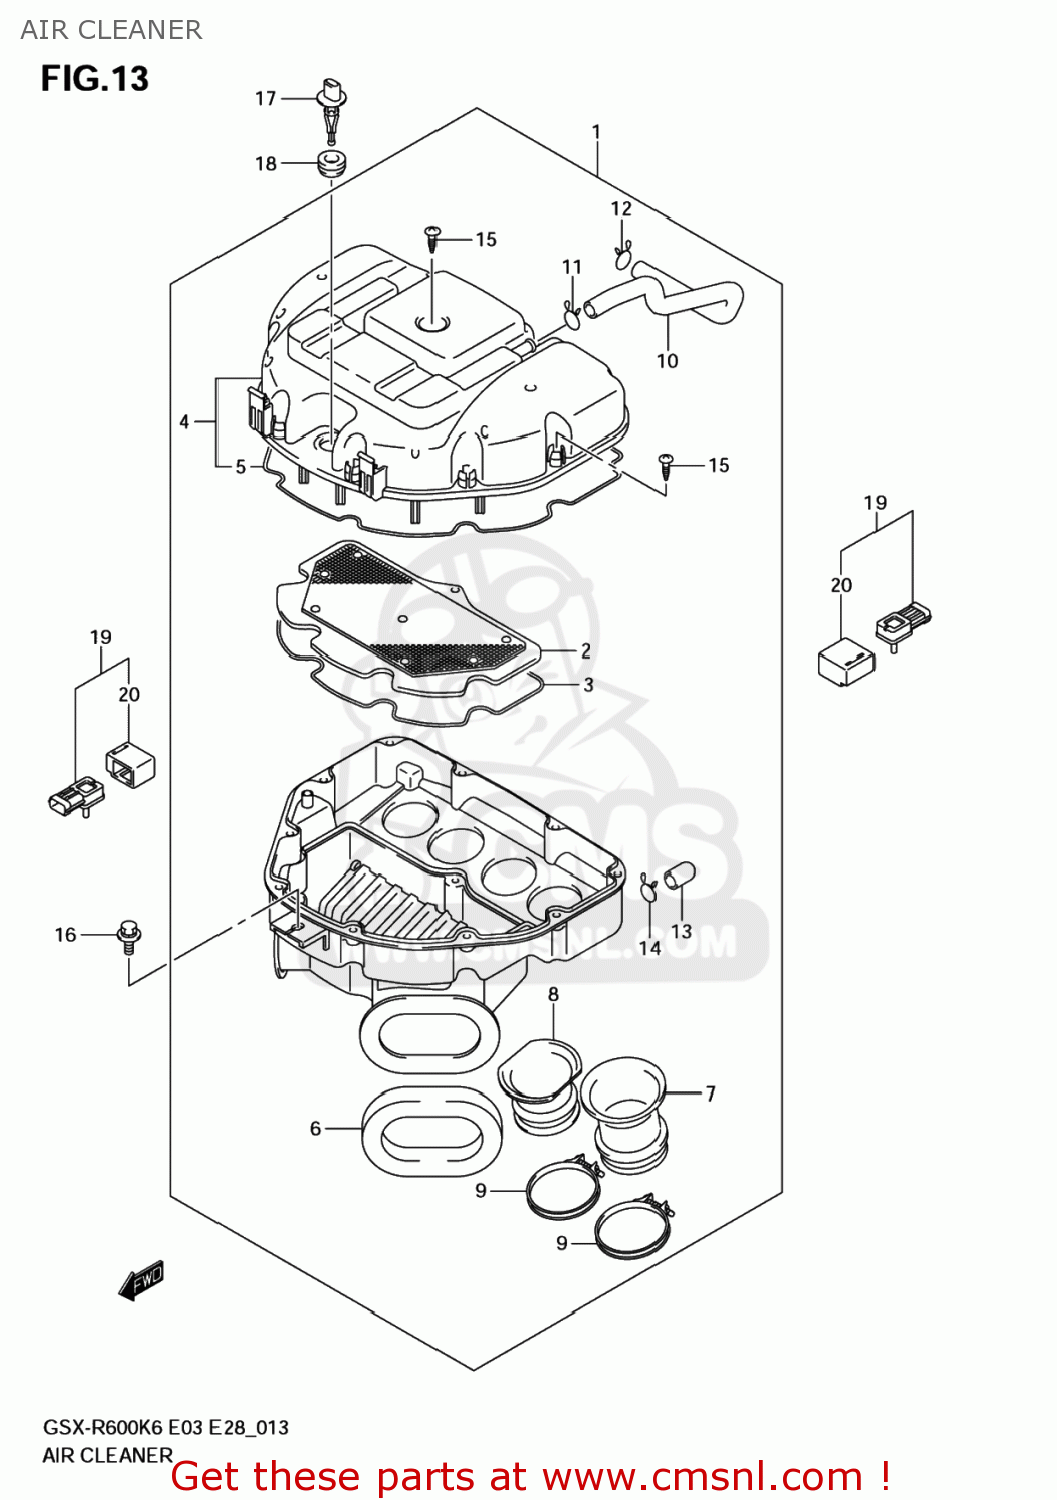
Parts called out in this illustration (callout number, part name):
1	CLEANER ASSY,A
2	FILTER ASSY
3	GASKET,CASE (NAS)
4	CAP,AIR CLEANER
5	GASKET,CAP (NAS)
6	CUSHION,DUCT
7	TUBE,OUTLET
8	TUBE,OUTLET
9	CLAMP
10	TUBE,BREATHER
11	CLIP
12	CLIP
13	PLUG
14	CLIP
15	SCREW
16	BOLT (6X16)
17	SENSOR,INLET AIR TEMP
18	GROMMET,AIR TEMP SENSOR
19	SENSOR,AIR PRESSURE
20	COVER
